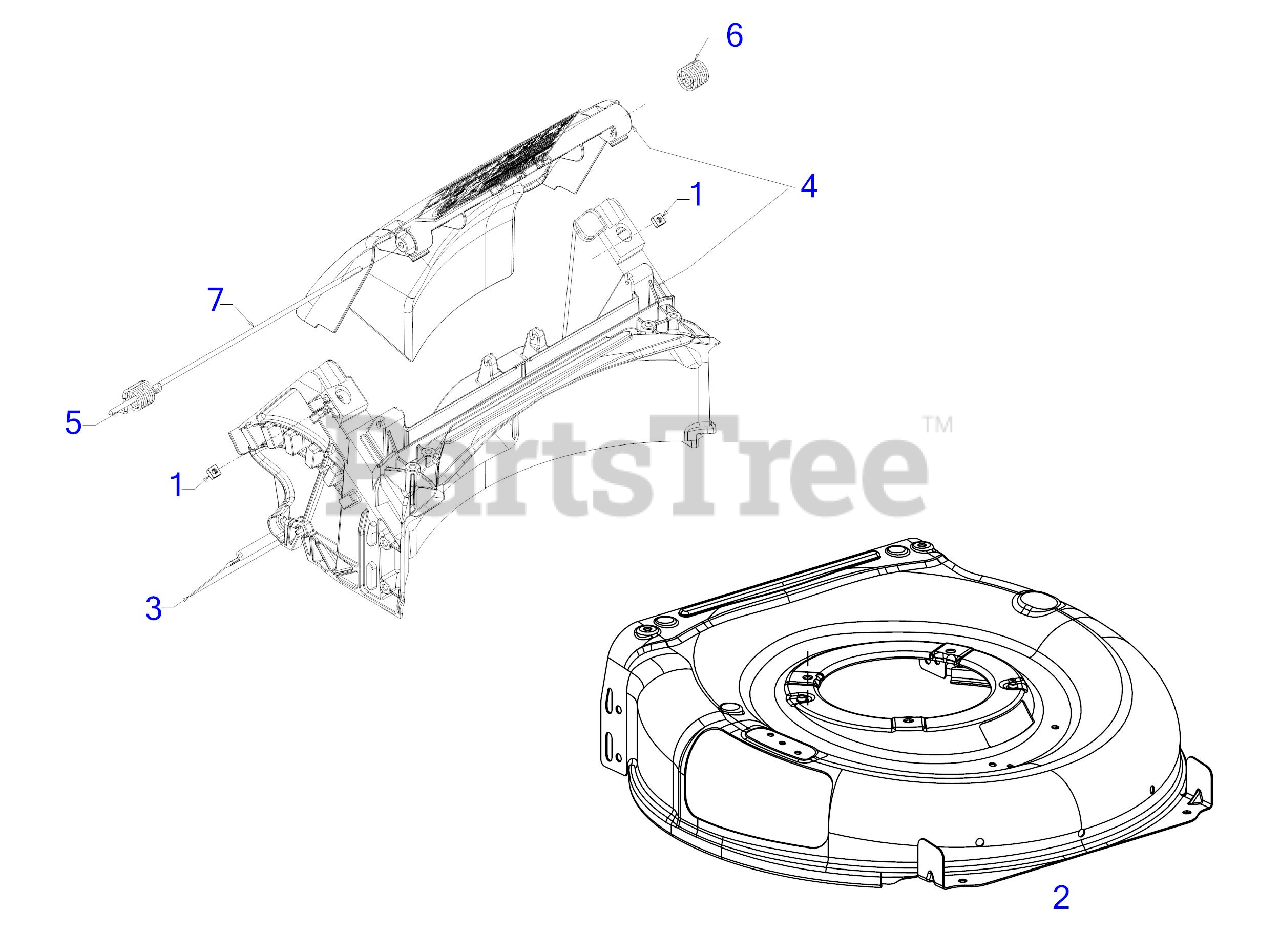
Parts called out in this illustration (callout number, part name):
1	SQUARE NUT 1/4-20
3	TRAILSHIELD
4	REAR BAG DOOR ASSEMBLY
5	TORSION SPRING (RH)
6	TORSION SPRING (LH)
7	REAR DOOR PIVOT ROD
